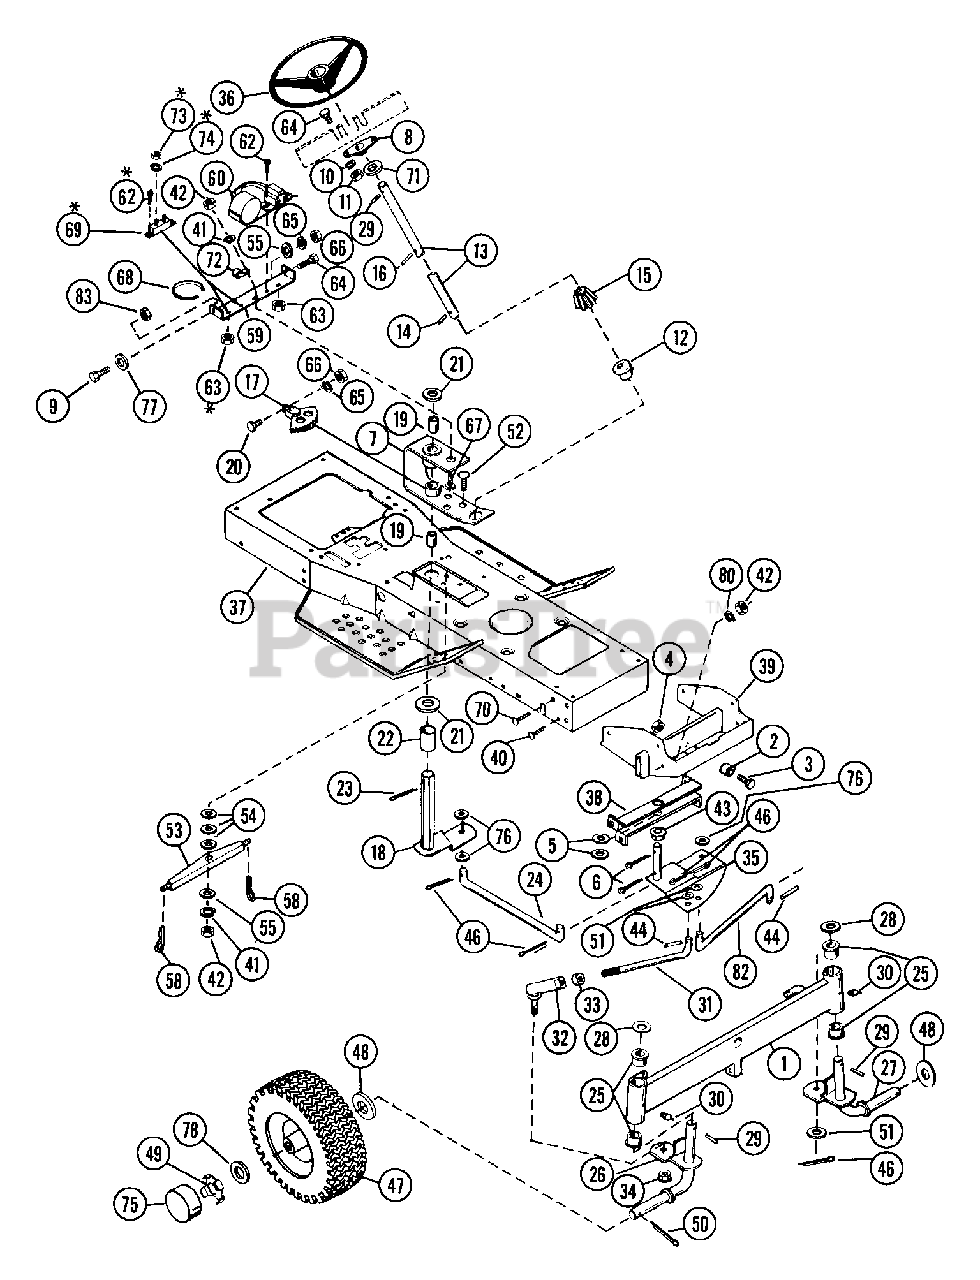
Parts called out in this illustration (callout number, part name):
1	FRONT AXLE WELDMENT
2	SPACER .531X.748X.524
3	BLT-HEX .50-13X1.25 PL GR5
4	NUT-LK-CROWN .50-13 GR C PL
5	WSHR-FL-STL.656X1.312X.095 PL
6	PIN-COTR .12 X 1.25 PL
7	STEERING BRACKET
8	BRG-FLG .751X2 HOLESX.81
9	BLT-HEX .31-18X1.25 PL GR5
10	WSHR-LK .312X.097 PL HVY
11	NUT-HEX .312-18
12	BSHG-FLG .750X1.093X.625X1.375
13	STEERING COLUMN
14	PIN .249X1.125 DRIV-LOK SP
15	PINION GEAR-STEERING
16	PIN-ROLL .188X1.13
17	STEERING BEVEL GEAR
18	ARM & SHAFT
19	BSHG-SLV .750X1.000X.750 HX SB
20	BLT-HEX .31-18X1.75 PL GR2
21	WSHR-FL-STL .875X1.250X.075
22	SPACER .780X.900X2.094
23	PIN-COTR .18X1.25 PL
24	STEERING LINK
25	SHEAVE 38 IN PAN
26	RIGHT SPINDLE WELDMENT
27	LEFT SPINDLE WELDMENT
28	WSHR-FL-STL .755X1.375X.093
29	PIN-ROLL .250X1.25
30	SPIN DRIVE ZERK FITTING
31	DRAG LINK
32	BALL JOINT R.H.
33	NUT-JAM .50-20 PL
34	NUT-LK .50-20 PL
35	STEERING PIVOT
36	STEERING WHEEL
37	FRAME W/DECALS
38	STEERING PIVOT CHANNEL
39	FRONT AXLE SUPPORT
40	BLT-RDHDSQNK .38-16X.75 SHT PL
41	WSHR-LK .375X.115 HVY PL
42	NUT-HEX .375-16
43	FLANGE BUSHING
44	PIN-ROLL .125X1.00
46	PIN-COTR .12X1.0 PL
47	WHEEL & TIRE ASSEMBLY
47	BRG-BALL .752X1.50X.50
48	WSHR-FL-STL .755X1.375X.093
49	SPINDLE CUP
50	PIN-COTR .25X1.50 ST PL
51	WSHR-FL-STL .520X.827X.062 YZ
52	BLT-RDHDSQNK .38-16X1.25 PL
53	PIVOT ARM
54	WSHR-FL-STL .380X.626X.033
55	WSHR-FL-STL.406X.812X.065PL
58	PIN-HAIR INT .08X.18X1.18
60	MODULE
61	CONNECTOR
62	SCR-MCH 10-24X.62 SLRH PL
63	NUT-KEPS 10-24 PL
64	BLT-HEX .31-18X.75 PL GR5
65	WSHR-LK .312X.097 PL HVY
66	NUT-HEX .312-18
67	BLT-HEX .38-16X1.00 PL
68	TIE DOWN
69	CIRCUIT BREAKER
70	BLT-RDHDSQSHNK .38-16X1.00 PL
71	WSHR-FL-STL .754X1.125X.062 PL
73	NUT 10-32 PL
74	WSHR-LK 10X.047 MED PL
75	HUB CAP
76	WSHR-FL-STL .505X.880X.072 PL
77	WSHR-FL-STL.312X.734X.065PL
78	WSHR-FL-STL .755X1.375X.062 PL
79	PIN-ROLL .250X1.75
80	WSHR-LK .375X.094 MED PL
81	WSHR-FL-STL .880X1.250X.062
82	DRAG LINK
83	NUT-LK-TOP .312-18 GR C PL
